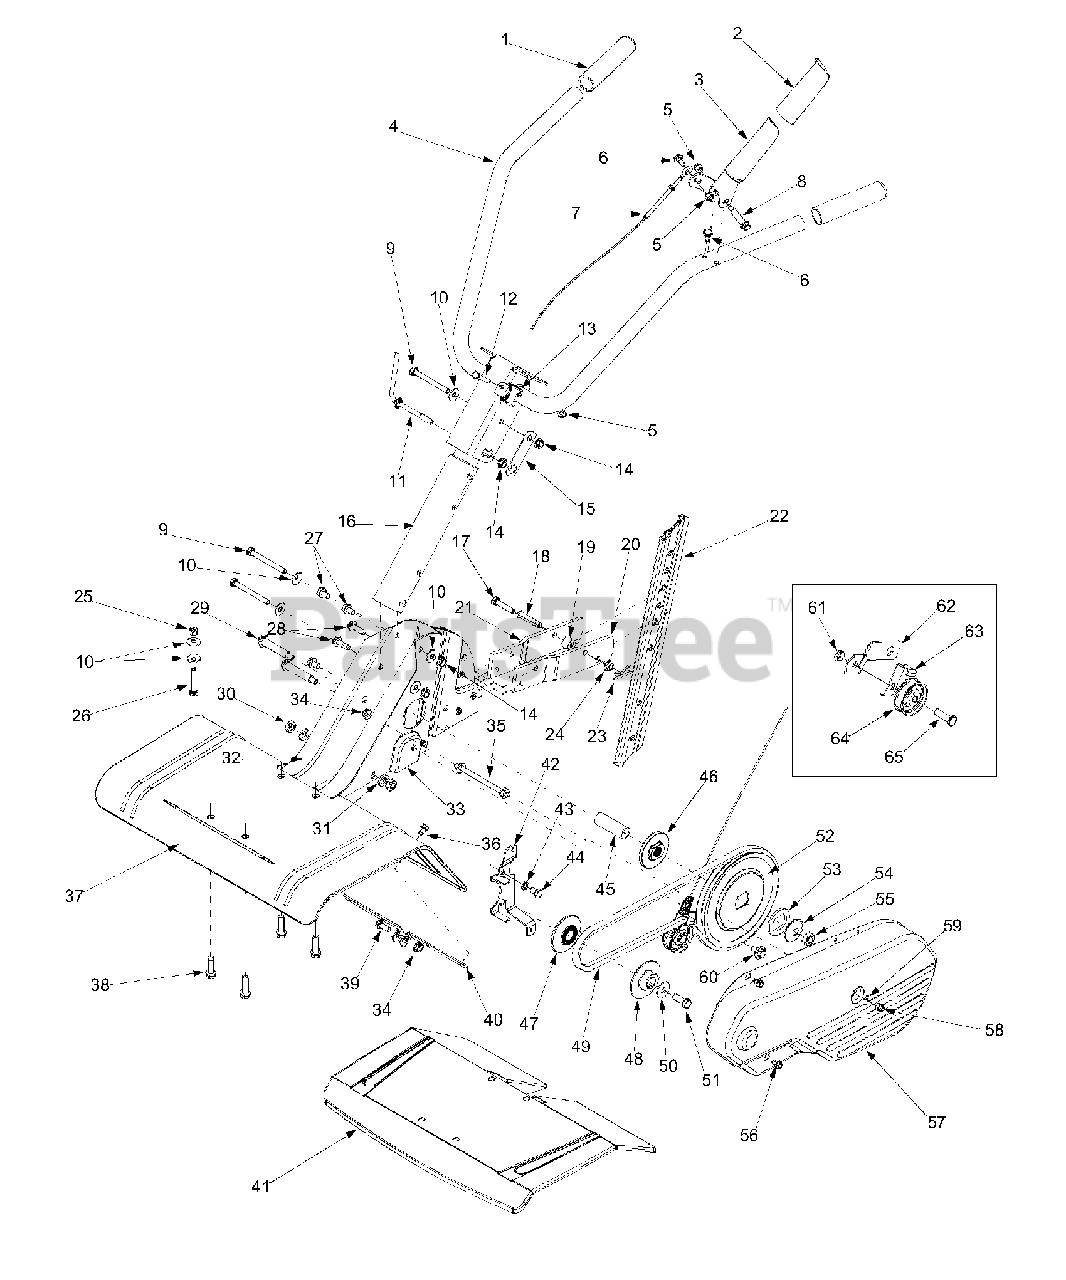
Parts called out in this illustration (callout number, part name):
2	Clutch Grip
5	Lock Nut Cap 1/4-20
6	Shoulder Screw
7	Clutch Cable
8	Shoulder Screw
9	Hex Cap Screw 5/16-18 x 3.0
10	Bell Washer .340 ID x .872 OD
11	Adjustable Handle Crank
12	Hex Cap Screw 1/4-20 x 1.5
13	Rope Guide
14	Flange Nut 5/16-18
15	Retainer Bracket
18	Clevis Pin 3/8 x 1.62
19	Spacer
23	Cotter Pin
24	Hex Flange Locknut 5/16-18
25	Hex Nut 5/16-18
26	Hex Cap Screw 5/16-18 x 1.75
27	Hex Washer Screw 5/16-18 x .625
28	Hex Washer Screw 5/16-18 x 1.0
29	Shoulder Screw
30	Jam Nut 7/16-20
31	Lock Washer 7/16
34	Flange Lock Nut 5/16-18
35	Belt Cover Belt
36	Hex Washer Screw 1/4-20 x .500
39	Hex Cap Screw 5/16-18
43	Lock Washer 5/16
44	Hex Cap Screw 5/16-24 x .50
45	Input Spacer .64 ID x 2.4 Lg
46	Pulley Adapter
47	Engine Inner Half Pulley
48	Engine Outer Half Pulley
49	Belt
50	Bell Washer .396 ID x 1.140 OD
51	Hex Cap Screw 3/8-24 x 1.0
52	Flat Pulley
53	Retainer Bearing Washer
54	Spherical Washer .531 ID x .620 OD
55	Jam Nut 1/2-20
56	Hex Washer Screw 1/4-20 x .50
58	Lock Nut Cap 1/4-28
59	Flat Washer .271 ID x .630 OD
60	Shoulder Screw
61	Jam Nut 3/8-16
63	Idler Keeper Bracket
64	Flat Idler
65	Hex Cap Screw 3/8-16 x 1.25
